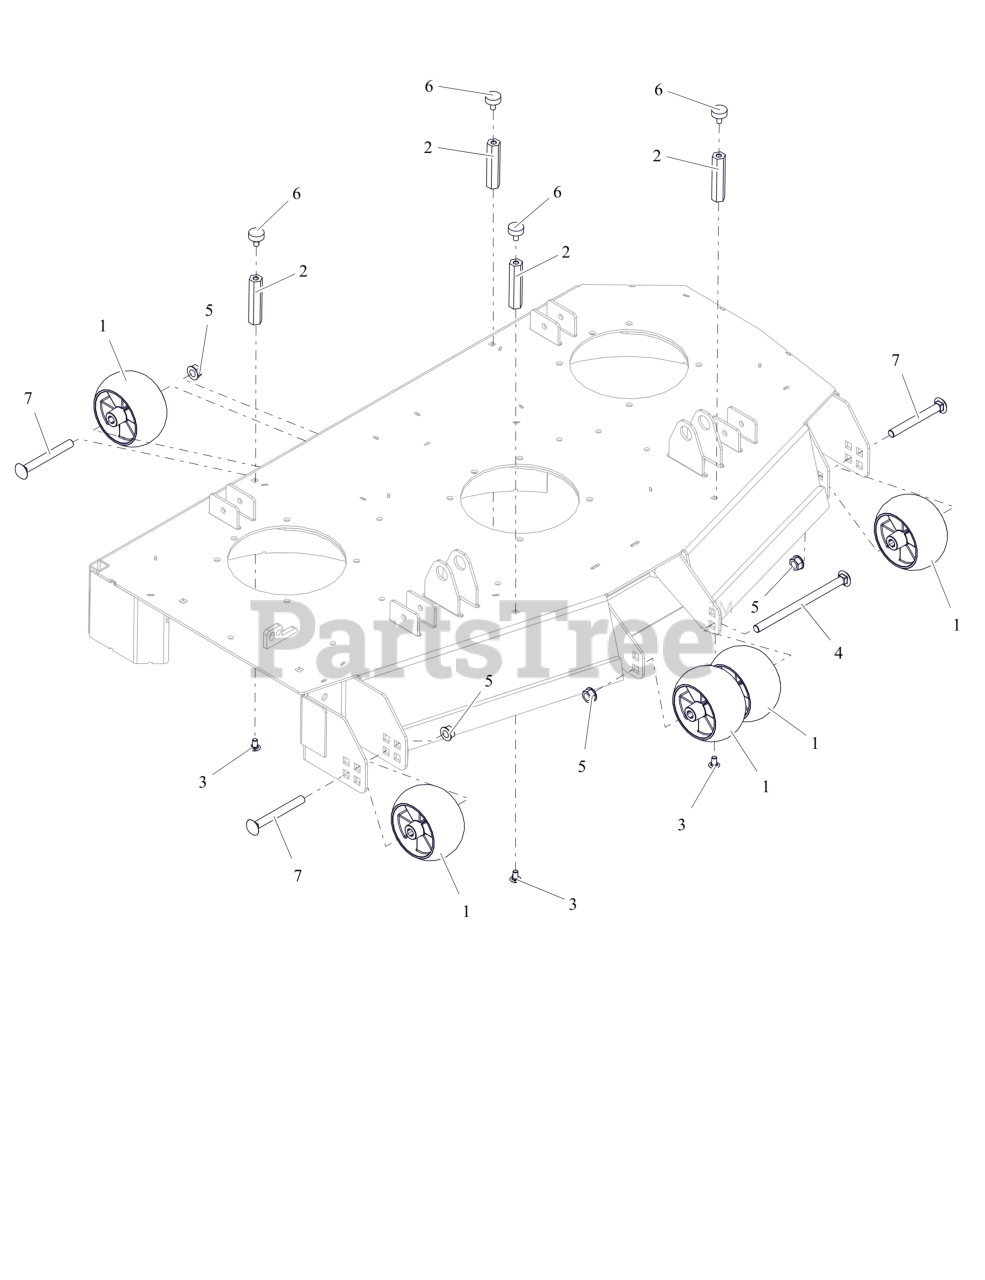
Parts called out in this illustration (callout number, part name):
1	WHEEL, ANTI SCALP - 5X3 CTR W/RIBS
2	NUT, COUPLING .312-18 X 3.375
3	BTL,RHSSN .313-18 X 0.625 G5 ZCC
4	BTL,RHSN .500-13 X 8 G5 ZCC
5	NUT-LK-CTR-FLG .500-13 GG ZCC
6	BUMPER, RUBBER
7	BLT,RHSN .50-13X4.50 G5 ZCC
